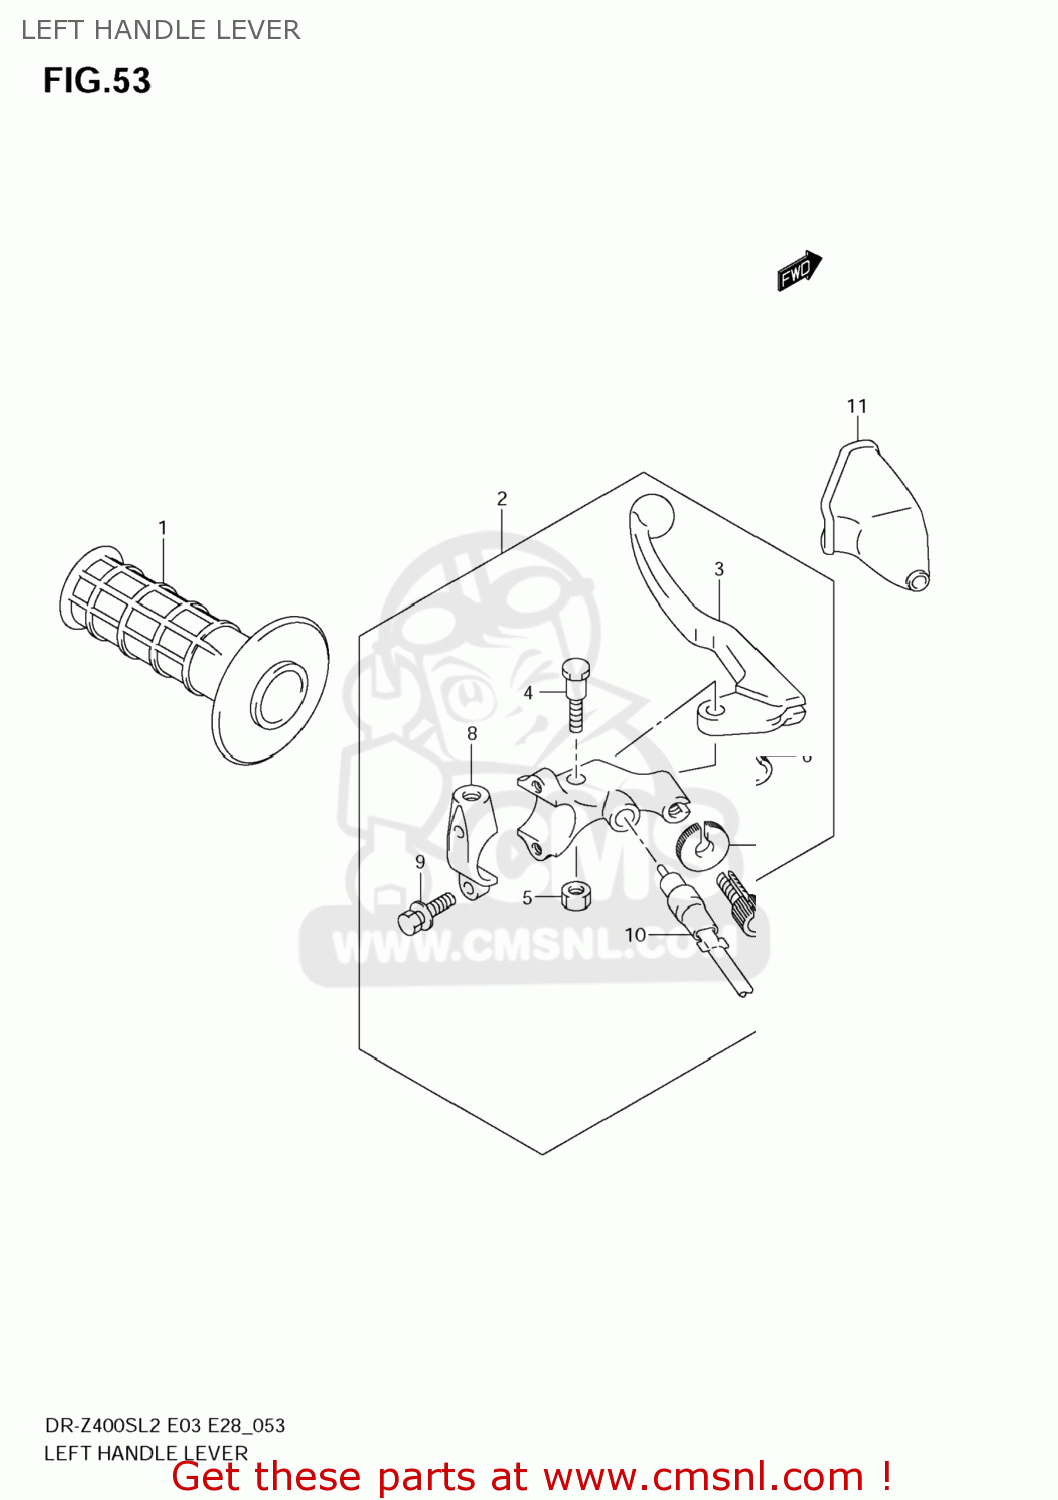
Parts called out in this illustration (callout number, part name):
1	GRIP,L
2	LEVER ASSY,CLUTCH
3	LEVER,CLUTCH
4	BOLT,LEVER PIVOT
5	NUT
6	ADJUSTER,WIRE
7	NUT,LOCK
8	BRACKET,HOLDER
9	BOLT,BRACKET
10	SWITCH ASSY,CLUTCH
11	COVER,CLUTCH CABLE DUST
